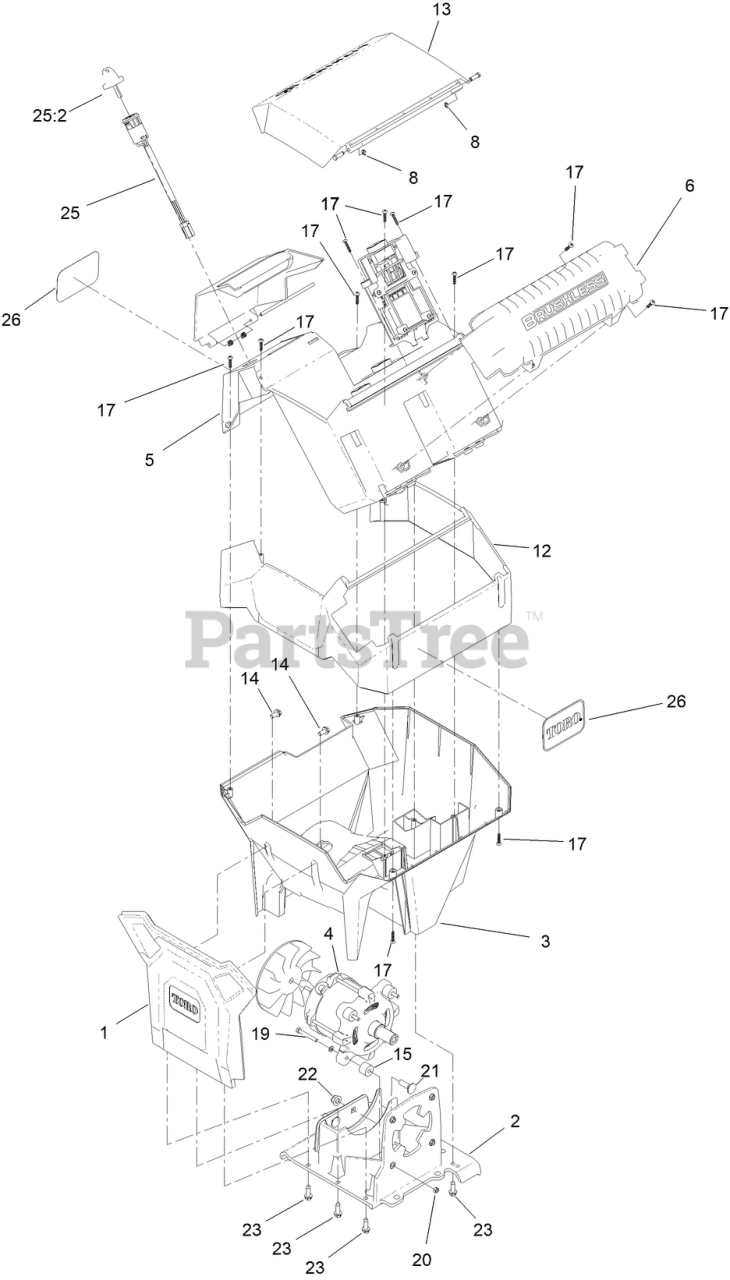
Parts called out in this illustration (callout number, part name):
1	BADGE-PLATE
2	MOUNT-POWERHEAD
3	HOUSING-MOTOR
4	MOTOR-60V, SNOWMASTER
5	BUCKET-BATTERY
6	MOTOR CONTROLLER ASM-POWERHEAD
8	RING-RETAINING
12	COVER-CONTROLLER
13	DOOR-TOP
14	SCREW-HWH
15	SPACER-MOTOR
17	SCREW-PPH
19	BOLT-M5X0.8MM X 40 MM LONG
20	NUT-HEX
21	BOLT-CARR
22	NUT-HF, NI
23	SCREW-HWHTF
25	IGNITION ASM-POWERHEAD
25:2	KEY-60V 2 STAGE POWER HEAD
